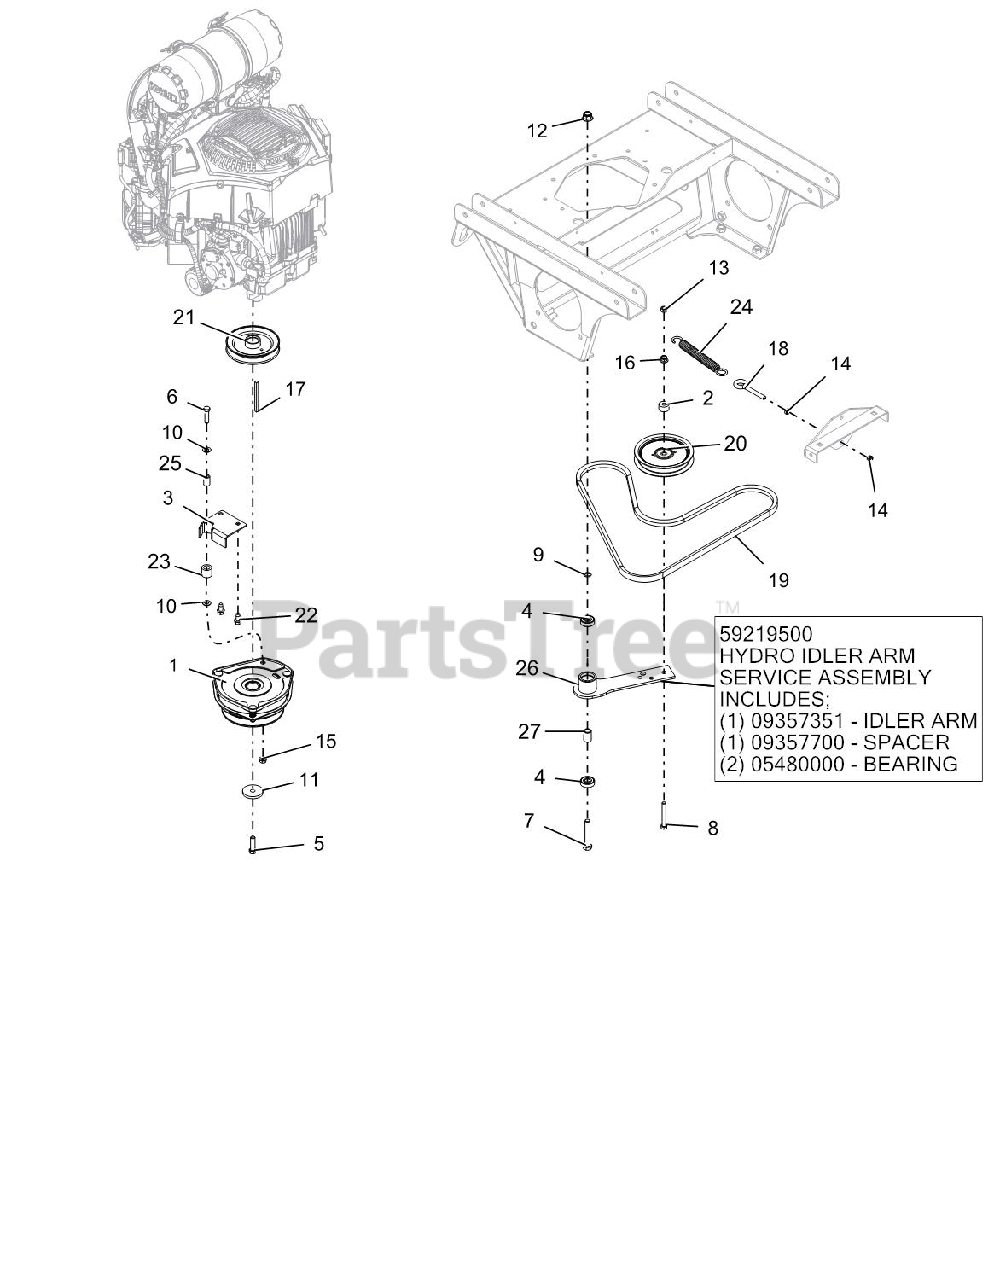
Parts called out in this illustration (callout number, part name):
1	CLUTCH, ELE-OGURA GT3.5-VP01R
2	SPACER .390X1.000X.562
3	CLUTCH STOP WLDMT - BLACK
4	BRG-BALL .500X1.38X.437
5	BLT-HEX .44-20X1.50 G5 YZ EP80
6	BLT-HEX .38-16X1.50 GR5 YWZC
7	BLT-HEX .50-13X3.00 GR5 YWZC
8	BLT-HEX .38-16X2.75 GR5 YWZC
9	WASHER, .500X.750X.020 THRUST
10	WSHR-FL-STL.406X.812X.065 YWZ
11	WSHR-FL-STL .469X2.00X.25 YWZC
12	NUT-LK-NYL-FLG .50-13 YWZC
13	NUT-LK-CTR .38-16 YWZC
14	NUT-HEX-JAM .375-16 YWZC
15	NUT-LK-TOP-FLG .38-16 YWZC
16	NUT-LK-NYL-FLG .38-16 YWZC
17	KEY-SQ. .25X3.50X.25 SAE
18	BLT-EYE .375-16X2.50 YWZC
19	V-BELT, COGGED B-RAW EDGE
20	IDLER, FLAT-5.00" (MACHINED)
21	SHEAVE-ENGINE 1.127ID X 5.25OD
22	SCR-TAP .38-16X.75 HWH TR YWZ
23	BUMPER,RUBBER .62X1.0X.88 LG
24	SPRING, EXTENSION
25	BUSH.,S.391X.622X.950 ST
26	BRG-BALL .50X1.38X.438 SEALED
26	SPACER .510 X .75 X 1.1485
26	HYDRO DRIVE IDLER ARM WMT- BLK
26	KIT, PRIMARY DECK IDLER ARM
27	SPACER .510 X .75 X 1.1485
